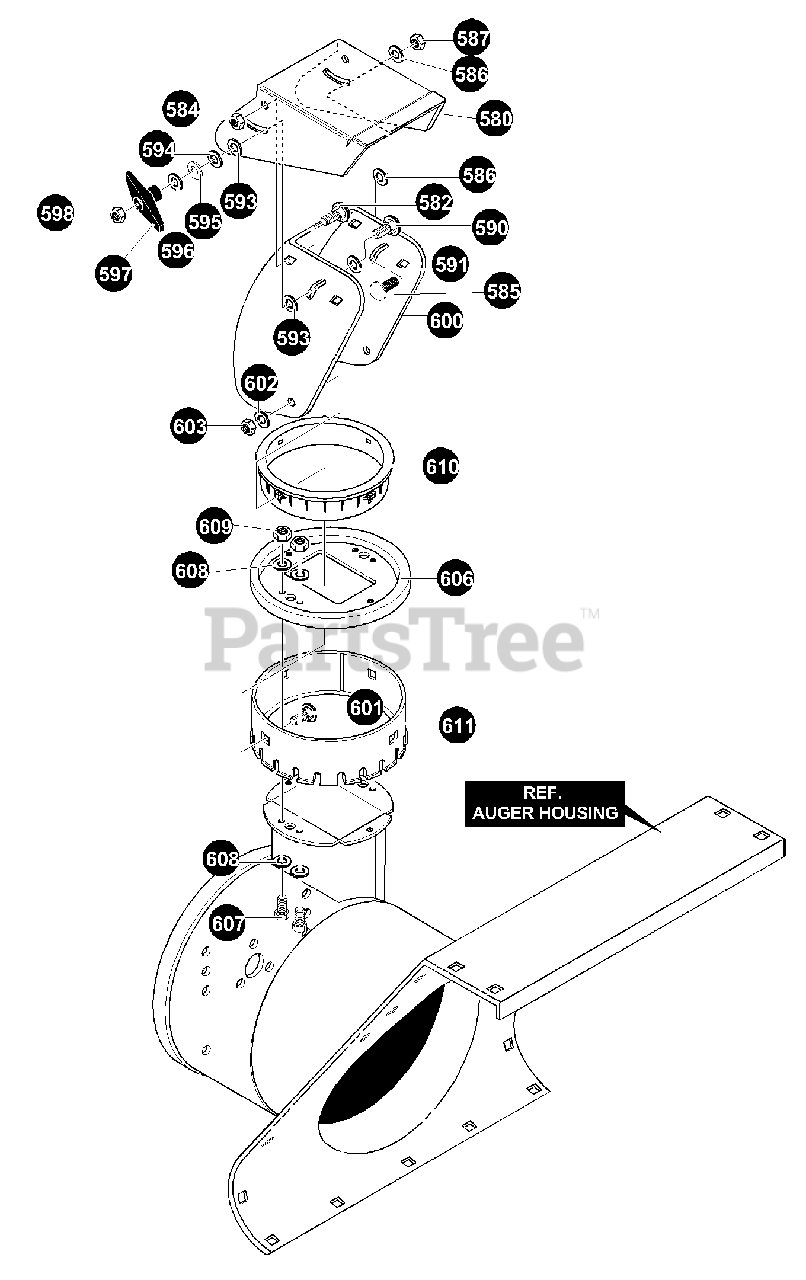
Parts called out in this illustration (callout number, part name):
580	CHUTE, UPPER
582	SCREW, 5/16-18X.75 SLTRMA
584	NUT, 5/16-18 HEXNYL
585	SCREW, 5/16-18X.75
586	WASHER, PLASTIC .315X.75X.064
587	NUT, 5/16-18 HEXNYL
590	BOLT, 5/16-18X1.00 CARR.
591	FLATWASHER .469X.92X.066
593	WASHER, PLASTIC .315X.75X.064
594	FLATWASHER .344X.69X.065
595	WASHER, HVSPTLK .328X.60X.09
596	FLATWASHER .344X.69X.065
597	KNOB, T 2 BLADE W/5/16-18 NUT
598	NUT 5/16-18 REGHEX
600	CHUTE, LOWER
601	BOLT 5/16-18X1.00 CARR.
602	FLATWASHER .344X.69X.065
603	NUT 5/16-18 HEXNYL
606	COLLAR, CHUTE RECT.
607	SCREW 1/4-20X.75
608	FLATWASHER, .281X.63X.065
609	NUT, 1/4-20 REGHEXCTRLK
610	RETAINER, RING INNER
611	RETAINER, RING OUTER
